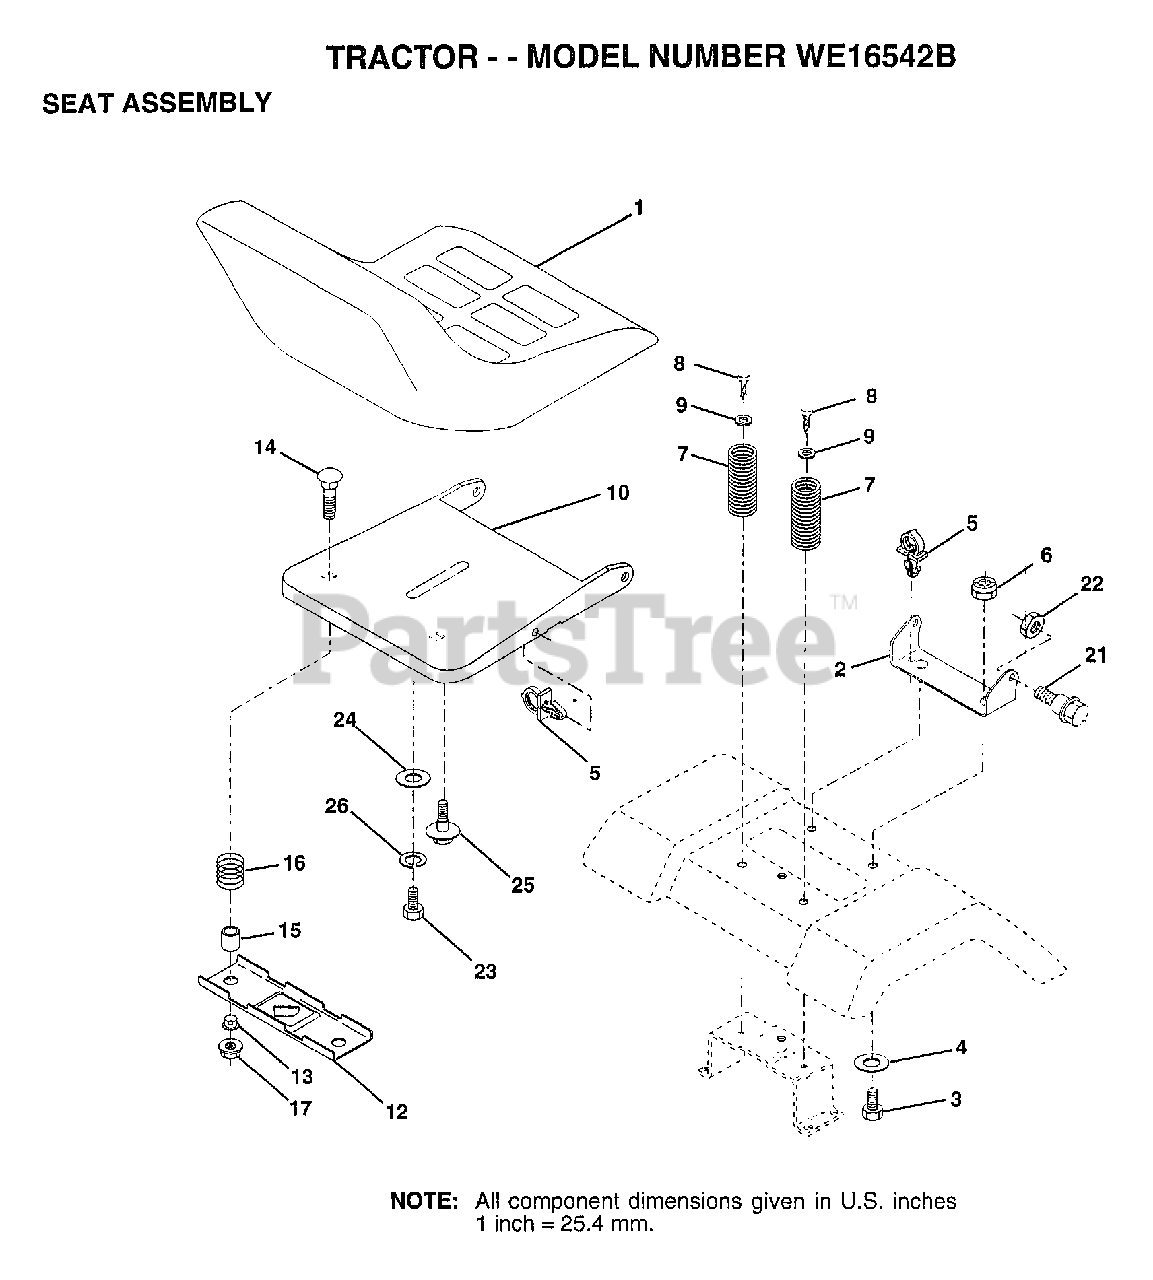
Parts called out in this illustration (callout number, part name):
2	BRACKET PVT SEAT
3	BOLT
4	WASHER PM
5	CLIP.PUSH-IN.HING
6	NUT
7	SPRING COMPRESSIO
8	SCREW GTV
9	WASHER
10	PAN-SEAT
12	BRKT SWITCH
13	BUSHING
14	BOLT-RD HD SQ NK
15	SPLIT SPACER
16	SPRING
21	"BOLT,SHOULDER"
22	NUT
23	BOLT
24	WASHER
25	"BOLT,SHOULDER"
26	LOCKWASHER
